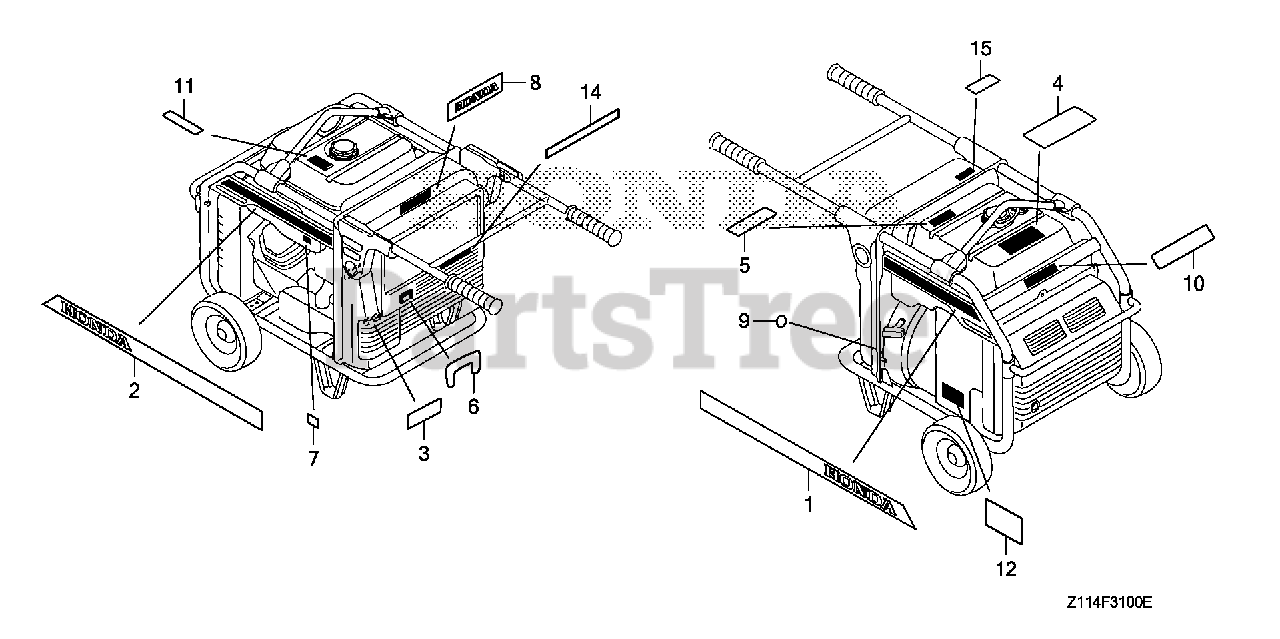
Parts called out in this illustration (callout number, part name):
1	MARK, EMBLEM (R)
2	MARK, EMBLEM (L)
3	MARK, BRANCH FUSE (E)
4	MARK, CAUTION (E)
4	LABEL, OPERATOR WARNING (E)
6	MARK, PANEL SWITCH
8	MARK, HONDA
9	MARK, GROUND
10	MARK, EX. CAUTION
11	PLATE, FUEL INDICATION
12	MARK, OIL CAUTION
